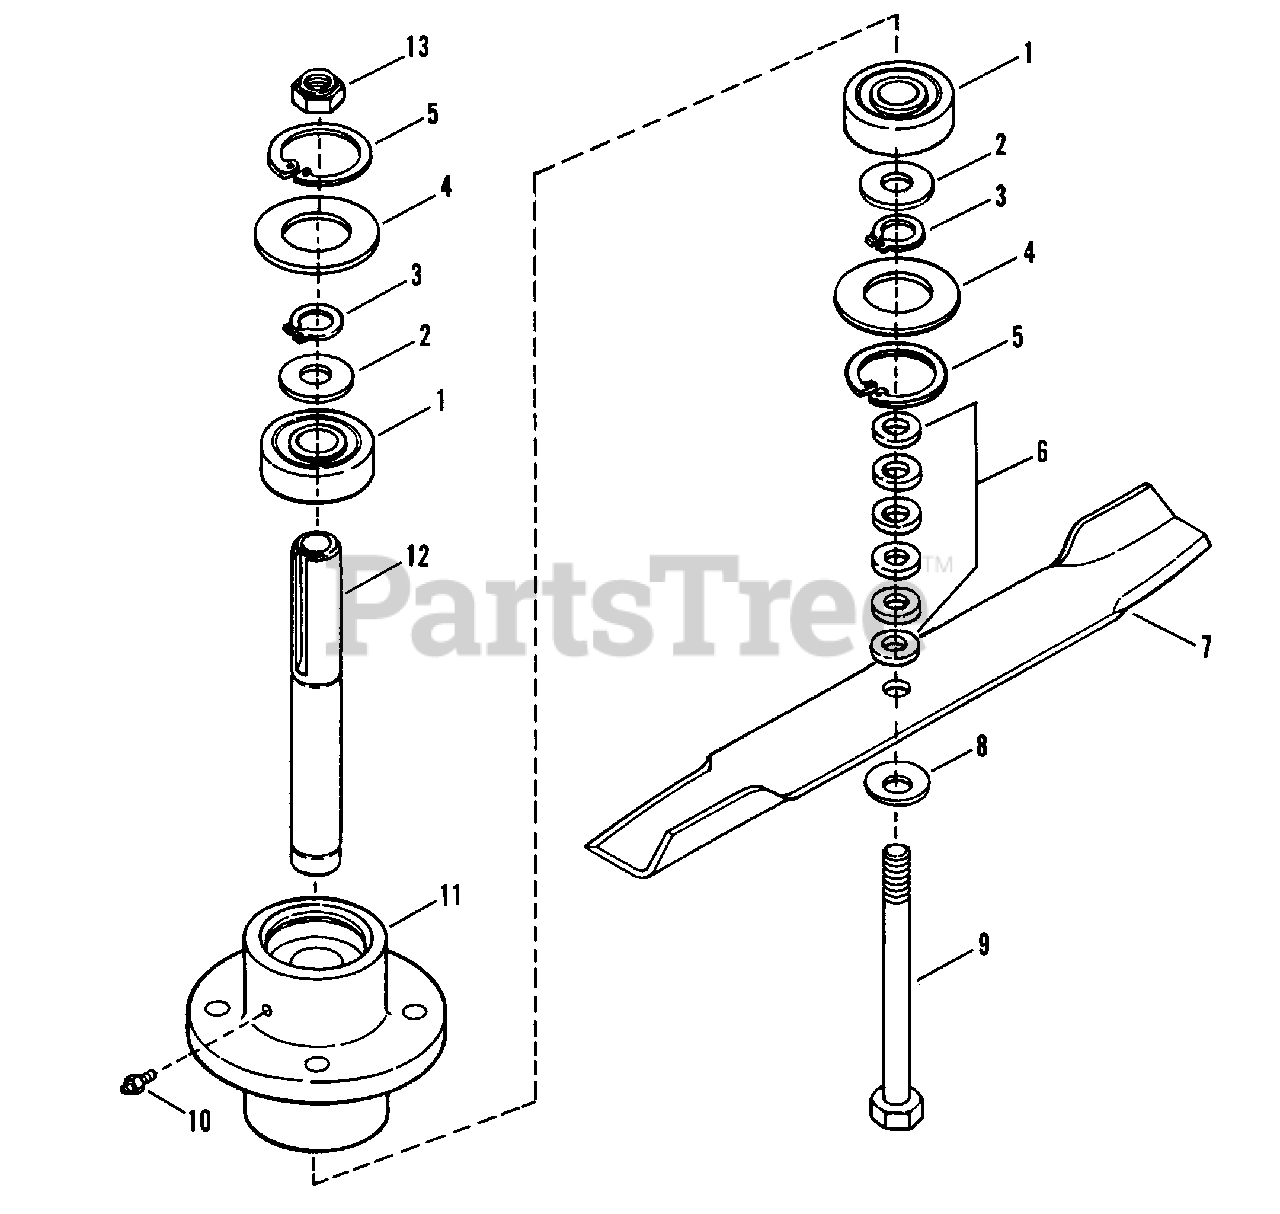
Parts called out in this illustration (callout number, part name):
1	BEARING, Sealed
2	WASHER, Spindle
3	SNAP-RING, Spindle Shaft
4	WASHER, Spindle Housing
5	SNAP-RING, Spindle Housing
6	SPACER, Blade
7	BLADE, 18", High Lift
8	WASHER, Beveled
9	BOLT, 5/8-18 x 9 3/4" Hex Head Cap, Grade 5
10	FITTING, Lube
11	HOUSING, Cutter
12	SHAFT, Spindle
13	NUT, 5/8-18 Hex
